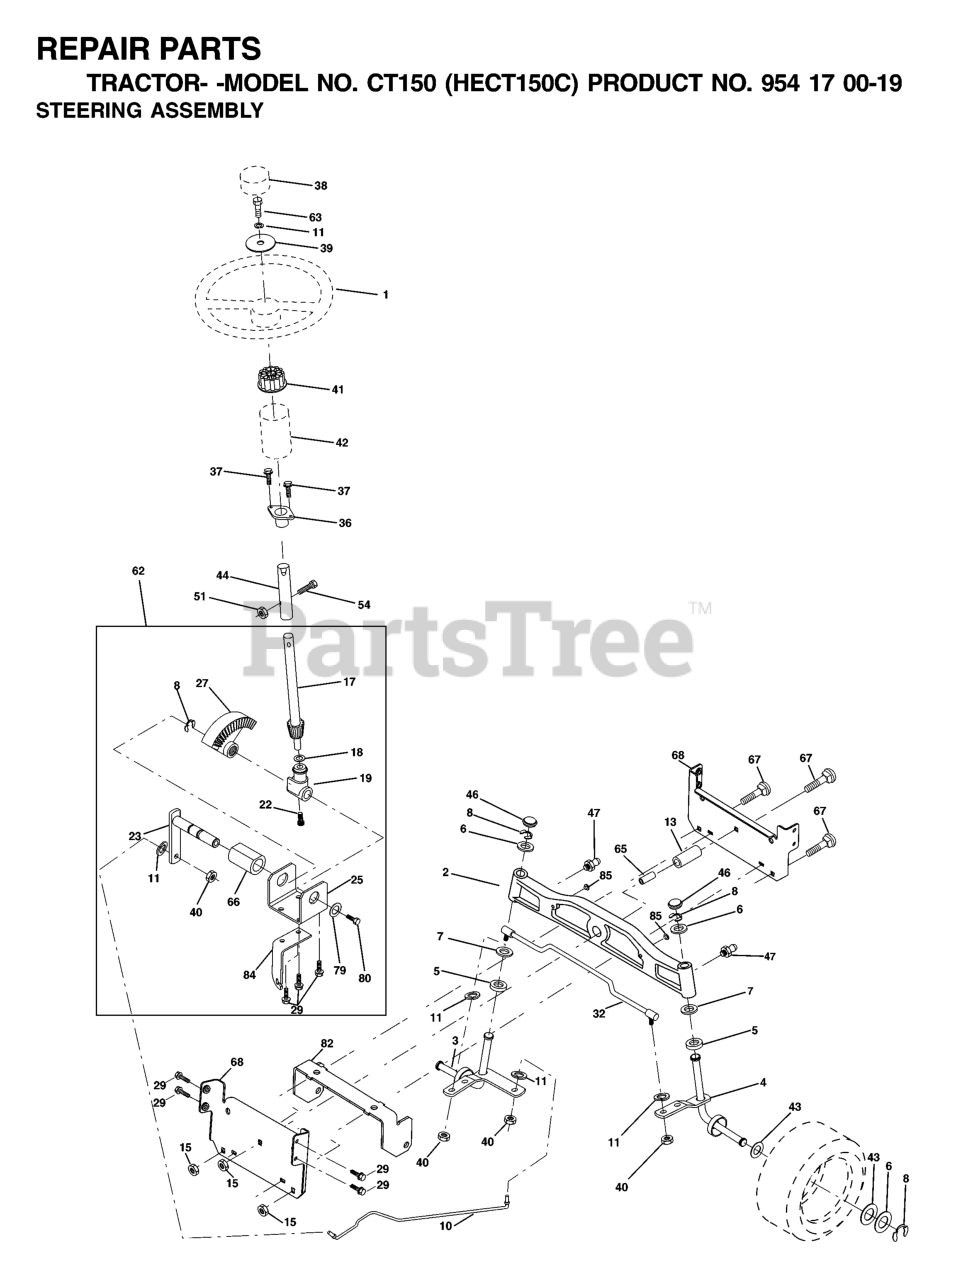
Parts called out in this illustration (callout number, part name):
1	STEERING WHEEL
2	AXLE ASM
3	SPINDLE.ASM.LH.15"TIRES
4	SPINDLE.ASM.RH.15"TIRES
5	THRUST WASHER
10	DRAGLINK.15".TIRES
11	WASHER, LOCK 3/8
13	TUBE, PIVOT AXLE
15	NUT
17	SHAFT ASM STEERING
18	THRUST WASHER
19	STEERING SHAFT SUPPORT
22	SCREW.HX.WSH.HD
23	SHAFT ASSY PITTMAN
25	BRACKET STEERING
27	GEAR.SECTOR
29	SCREW 3/8-16X3/4
32	ROD.ASM.TIE.BALL.JOINT.NOVAN
33	WASHER M
34	WASHER.LOCK.HVY.HLCL.SPR.5/16
35	NUT, CROWNLOCK
36	BUSHING, STEERING
37	SCREW.TT.#10-32X.5.3/8.FLANGE
38	CAP.WHEEL.STEERING.GREY
39	Washer 13/32 x 1-1/20 x 11 Gauge
40	GRIPCO NUT
41	STEERING WHEEL ADAPTOR
42	BOOT STEERING
44	EXT SHAFT STEERING
46	CAP.SPINDLE.BLACK
51	NUT.71038.31-18.HEX.NYLOCK
54	BOLT.5/16-18X1-1/4 FULL.THREAD
62	STEERING KIT
65	SPACER BRACE AXLE
66	BEARING ARM
67	BOLT
68	BRACE.AXLE.15"TIRES
79	WASHER
80	BOLT.HX.NYLON3/8-16X
82	BRACKET
84	Bracket Cable Clutch Chassis
85	FASTENER.XMAS.TREE
86	SPRING.RETAINER.YELLOW.ZINC
87	WASHER, FLAT .781 X 1 1/2"
